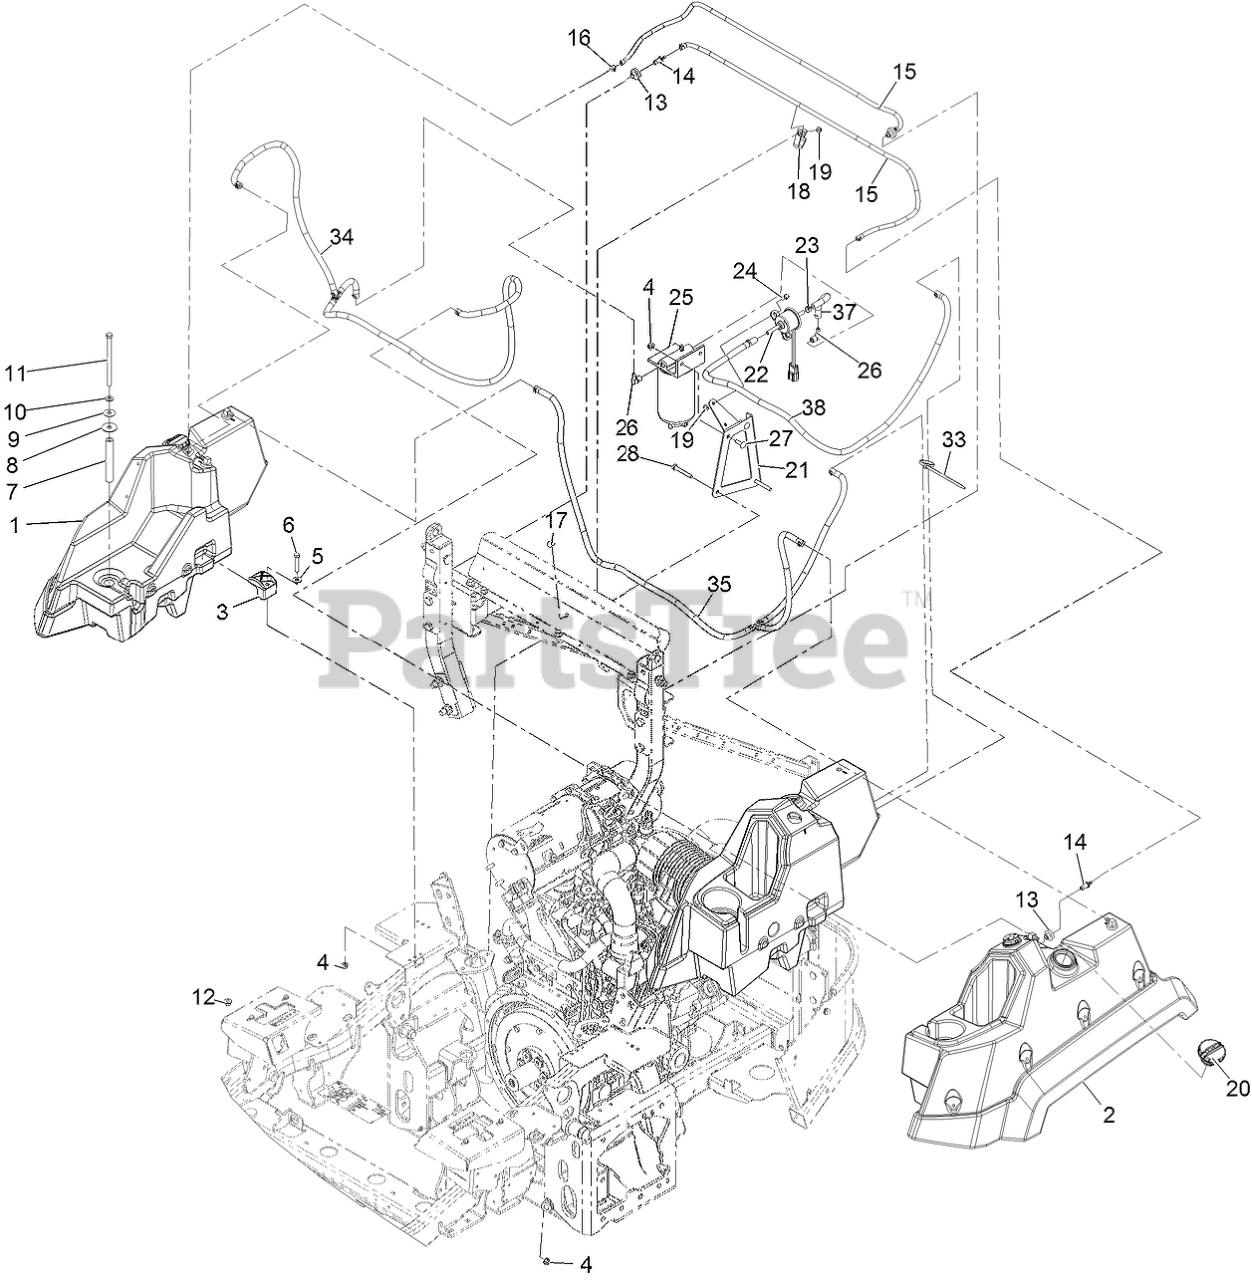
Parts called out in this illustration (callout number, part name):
1	RH FUEL TANK ASM
2	LH FUEL TANK ASM
4	NUT-HF, NI
5	WASHER-FLAT
6	SCREW-HH
7	TUBE-SPACER
8	WASHER-RUBBER
9	WASHER-PLAIN
10	WASHER-FLAT
11	SCREW-HH
12	NUT-HF, NI
13	BUSHING
14	FITTING-ORIFICE, STRAIGHT
15	HOSE-VENT, TANK
16	CLAMP-HOSE
17	SCREW-CARR
18	CLAMP-HOSE
20	CAP-FUEL, DIESEL
21	BRACKET-FILTER, FUEL
22	PUMP-FUEL, ELECTRIC
23	CLAMP-HOSE
24	SCREW-HWH
25	FILTER-WATER/FUEL SEPERAT
26	FITTING-HYD, 90
27	SCREW-CARR
28	SCREW-HH
33	TIE-PLASTIC
34	FUEL SUCTION LINE ASM
35	FUEL RETURN LINE ASM
37	HOSE-FUEL
38	HOSE-FUEL
